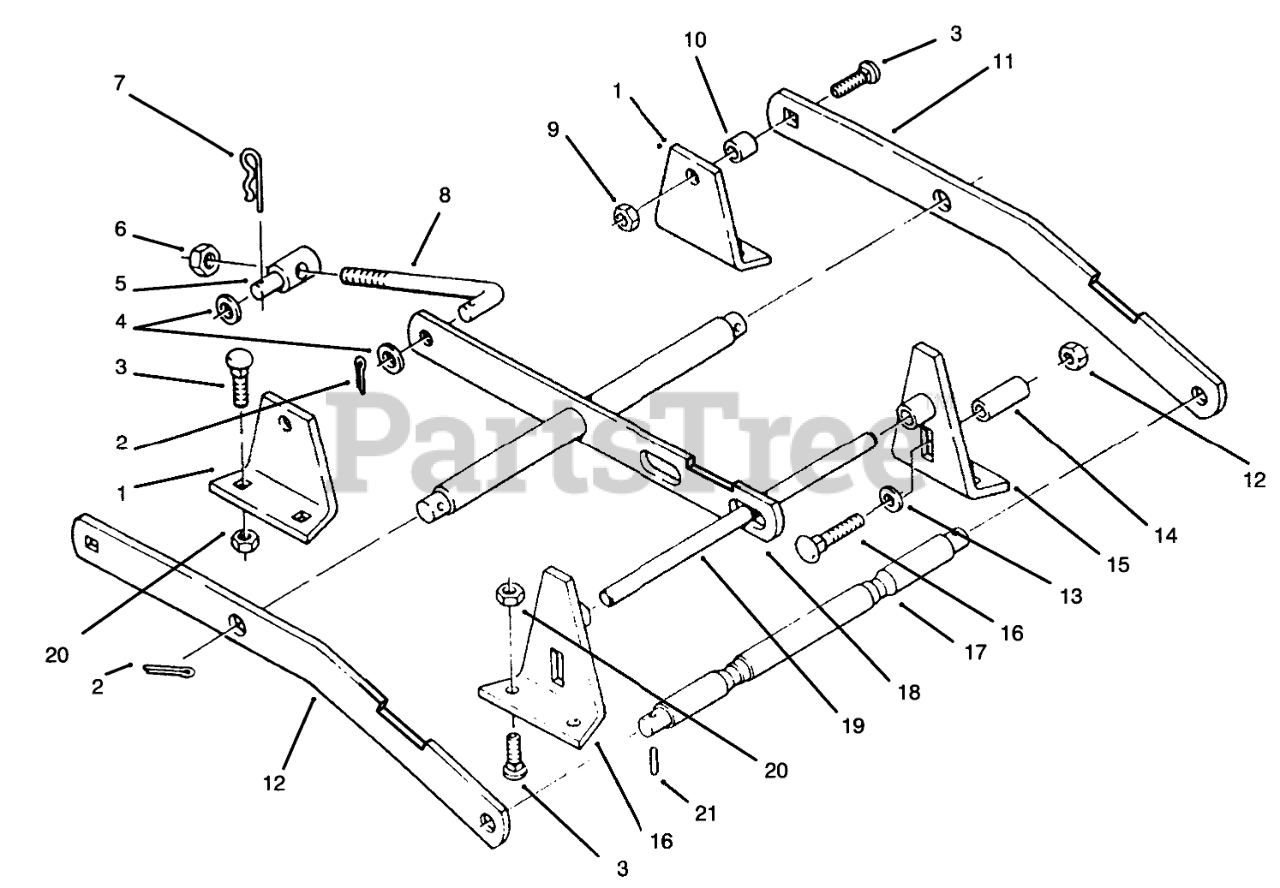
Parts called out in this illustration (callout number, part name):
1	Rear Deck Bracket
2	PIN-COTTER
3	BOLT-CARR
4	WASHER-FLAT
5	Trunnion
6	NUT-LOCK, NI
7	PIN-HAIR
8	ROD LEVELER
9	LOCKNUT-FLANGE
10	SPACER
11	Bar-Draft
12	NUT-LOCK, NI
13	WASHER-FLAT
14	SPACER
15	Front Deck Bracket
16	BOLT-CARR
17	Shaft
18	Leveler
19	Front Shaft
20	NUT-LOCK, NI
